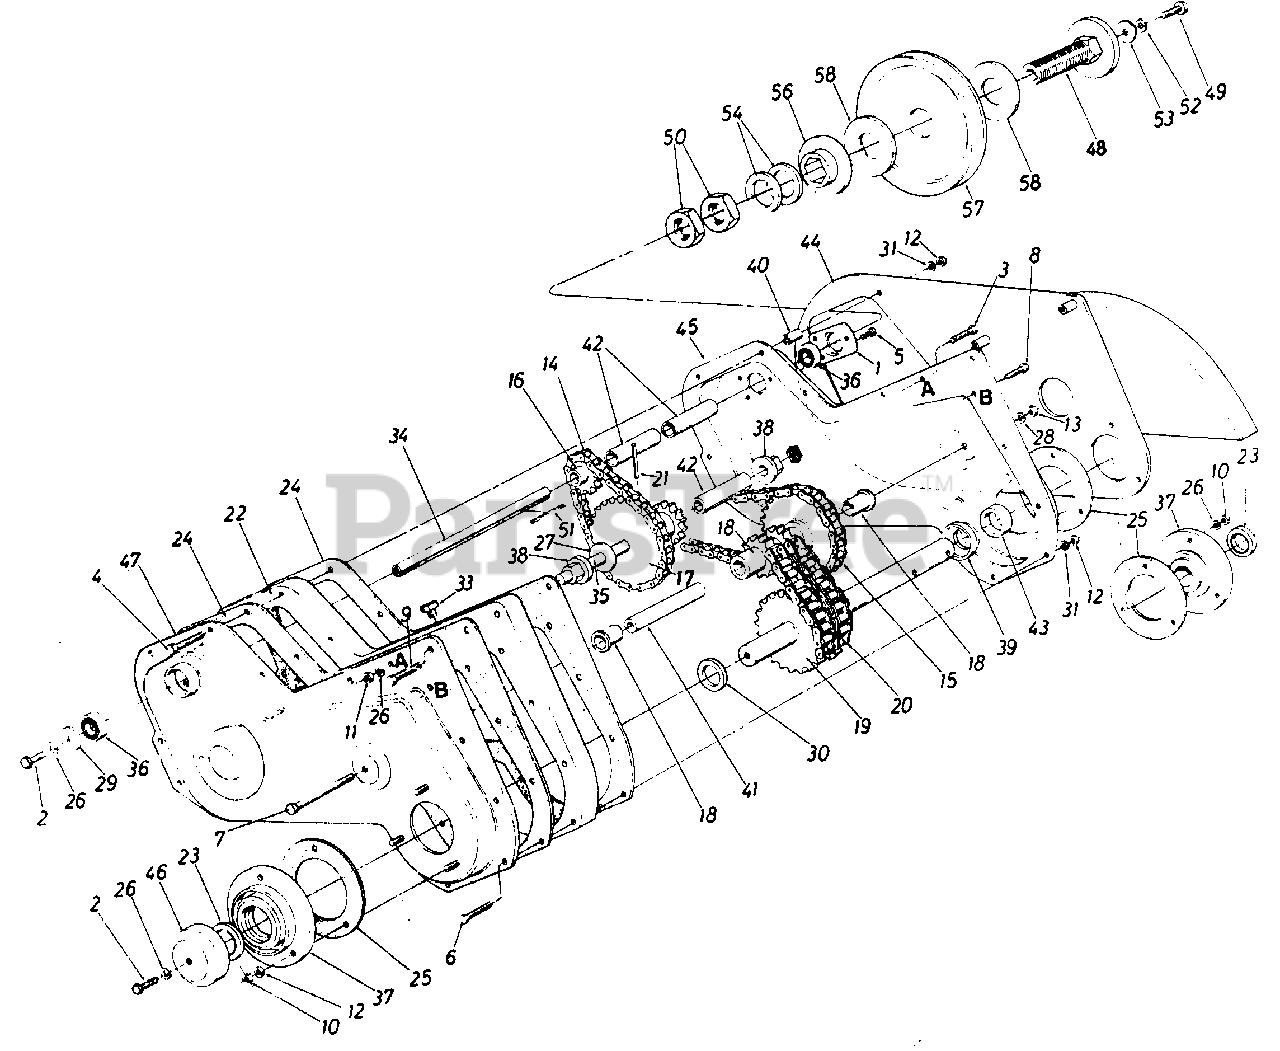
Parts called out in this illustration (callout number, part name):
1	Bearing Housing 1-3/8" Dia.
2	Hex Bolt 5/16-18 x .88" Lg. Spec.
3	Hex Bolt 5/16-18 x 1.50" Lg.
4	Hex Bolt 1/4-20 x 2.75" Lg.
5	Hex Wash. S-Tap. Scr. 1/4-20 x .50" Lg.
6	Hex Bolt 1/4-20 x 1.50" Lg.
7	Hex Bolt 3/8-16 x 4.5" Lg.
8	Hex Wash. Hd. Bolt 1/4-20 x 1.5" Lg.
9	Hex Wash. TT-Tap Scr. 5/16- 18 x 1.75" Lg.
10	Hex Cent. L.-Nut 5/16-18 Thd.
11	Hex Nut 5/16-18 Thd.
12	Hex Nut 1/4-20 Thd.
13	Hex Nut 3/8-16 Thd.
14	#41 Chain 1/2" Pitch x 34 Links- Endless
15	#42 Chain 1/2" Pitch x 48 Links- Endless
16	Sprocket 10 Tooth .500" Pitch
17	10 & 28 Teeth Sprocket Ass'y.
18	8-2 & 28 Sprocket Sleeve Ass'y
19	18-2 Sprocket Shaft Ass'y.
20	#50-2 Chain 5/8" Pitch x 28 Links- Endless
21	Spring Pin Spir. 1/4" Dia. x 1.50" Lg.
22	Spacer Block-Tiller Housing
23	Oil Seal Double Lip-1-1/4" Dia.
24	Gasket for Tiller Housing
25	Gasket for Brg.-Housing
26	L.-Wash. 5/16" I.D.
27	Fl.-Wash. .640" I.D. x 1.24" O.D.
28	L.-Wash. 3/8" I.D. Heavy Duty
29	Fl.-Wash. .344" I.D. x.1.125"
30	Special Washer
31	L.-Wash. 1/4" I.D.
33	Vent Plug
34	Jack Shaft .525" I.D. x 7.78 " Lg.
35	Sprocket Shaft .63" Dia. x 5.0" Lg.
36	Ball Brg. .62" I.D. x 1.38" O.D.
37	Bearing Housing- 1-1/4"
38	Hex Flange Brg.
39	Spacer 1.25" I.D. x 2.0" O.D.
40	Spacer.28" I.D. x .62" O.D. x .90" Lg.
41	Spacer .38" I.D. x .62" O.D. x 3.44" Lg.
42	Spacer.62" I.D. x .88" O.D. x 1. 56 " Lg.
43	Spacer 1.25" I.D. x 1.62" O.D. x . 50" Lg.
46	Dust Cap .320" Dia. Hole
49	Hex Bolt 5/16-18 x 1.25" Lg. Grade 5
50	Hex Jam Nut 1.0-14 x 28 Thd.
51	Sq. Key 3/16 x 1.50" Lg.
52	L.-Wash. 5/16" I.D.
53	Fl.-Wash. .344" I.D. x 1.125" 0. D.
54	Spring Bell Wash. 1.0" I.D. x 2.0" O.D.
56	Floating Disc 3-1/4" O. D. x 1.0" I.D.
57	5/8 V-Pulley 1.50" I.D. x 6.50"
58	Friction Pad 3-1/4" O.D. x 1-3/8" I.D.
